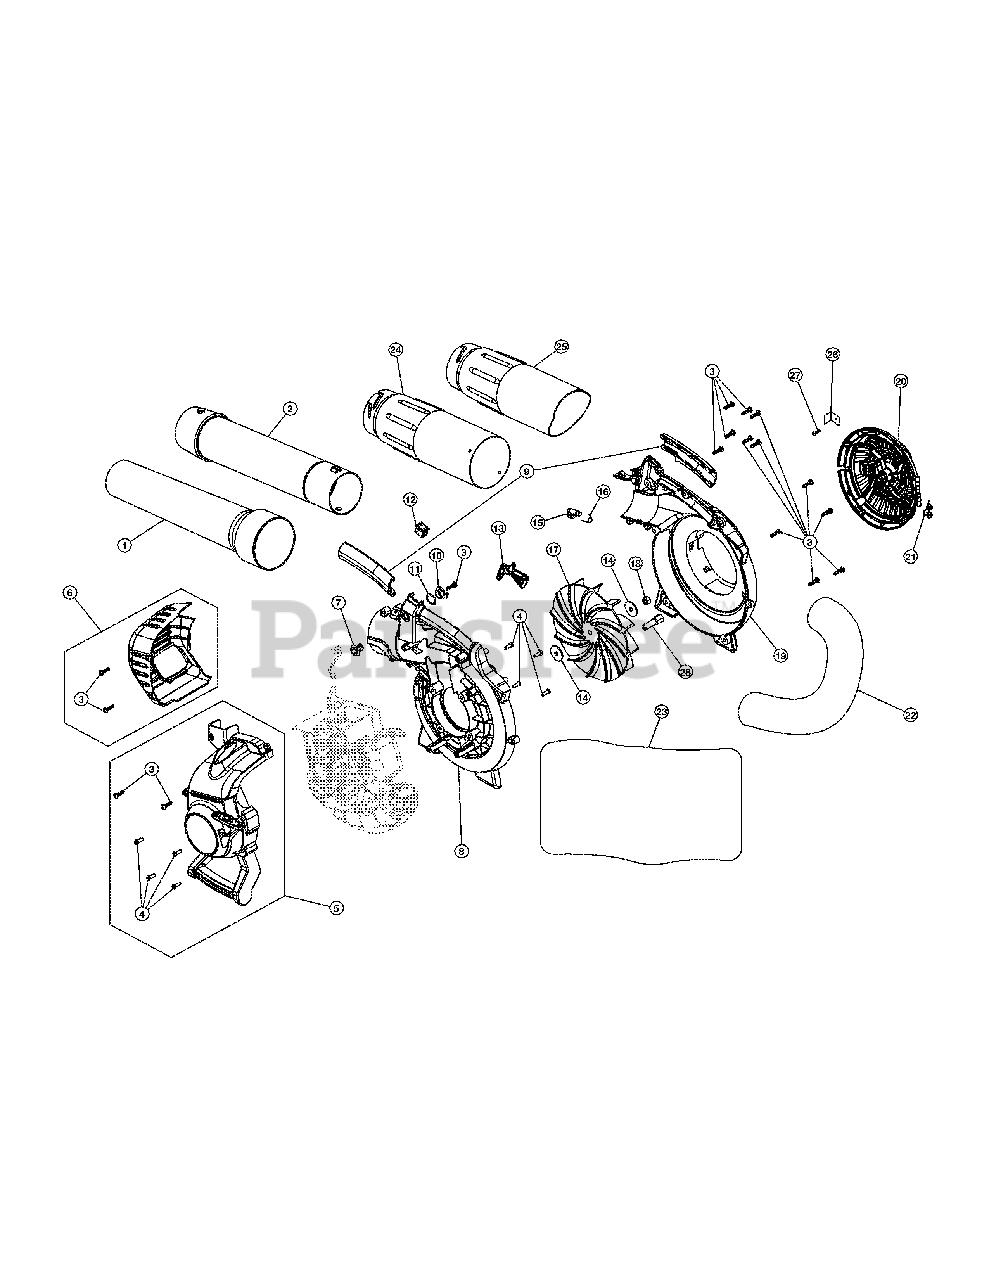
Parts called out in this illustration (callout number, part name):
1	Lower Tube
2	Upper Tube
4	Screw
5	Engine Cover Assembly
6	Muffler Cover Assembly
7	Outer Trigger Lock
8	Impeller Housing
9	Handle Grips
10	Inner Trigger Lock
11	Wavey Washer
13	Throttle Trigger
14	Washer
15	Latch Tube
16	Latch Spring
17	Impeller
18	Nut
19	Impeller Housing
20	Intake Cover
21	Spring
24	Upper Vac Tube
25	Lower Vac Tube
26	Door Lock
27	Screw
28	Adapter
